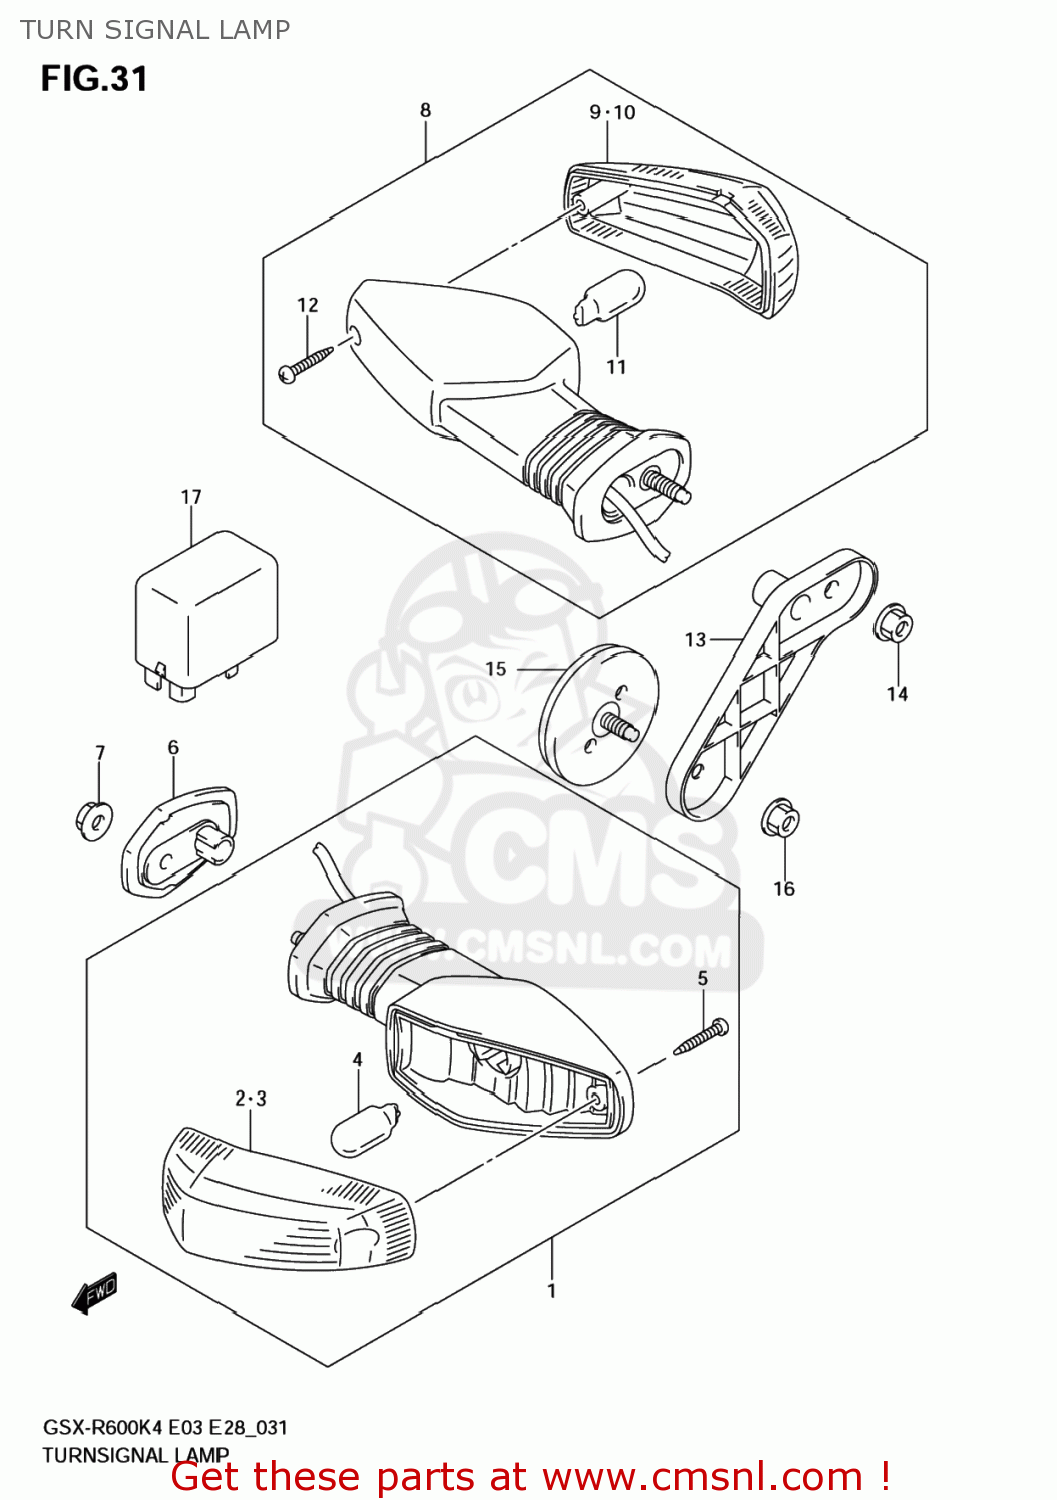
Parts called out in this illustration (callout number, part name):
1	LAMP ASSY,FR TURN SIGNAL,R
2	LENS
3	LENS
4	BULB(12V18W)
5	SCREW
6	PLATE,FR TURNSIGNAL
7	NUT
8	LAMP ASSY,RR TURNSIGNAL,R
9	LENS
10	LENS
11	BULB(12V18W)
12	SCREW
13	PLATE,RR TURN SIGNAL,R
14	NUT
15	REFLECTOR ASSY,RR SIDE
16	NUT
17	RELAY ASSY,TURNSIGNAL
